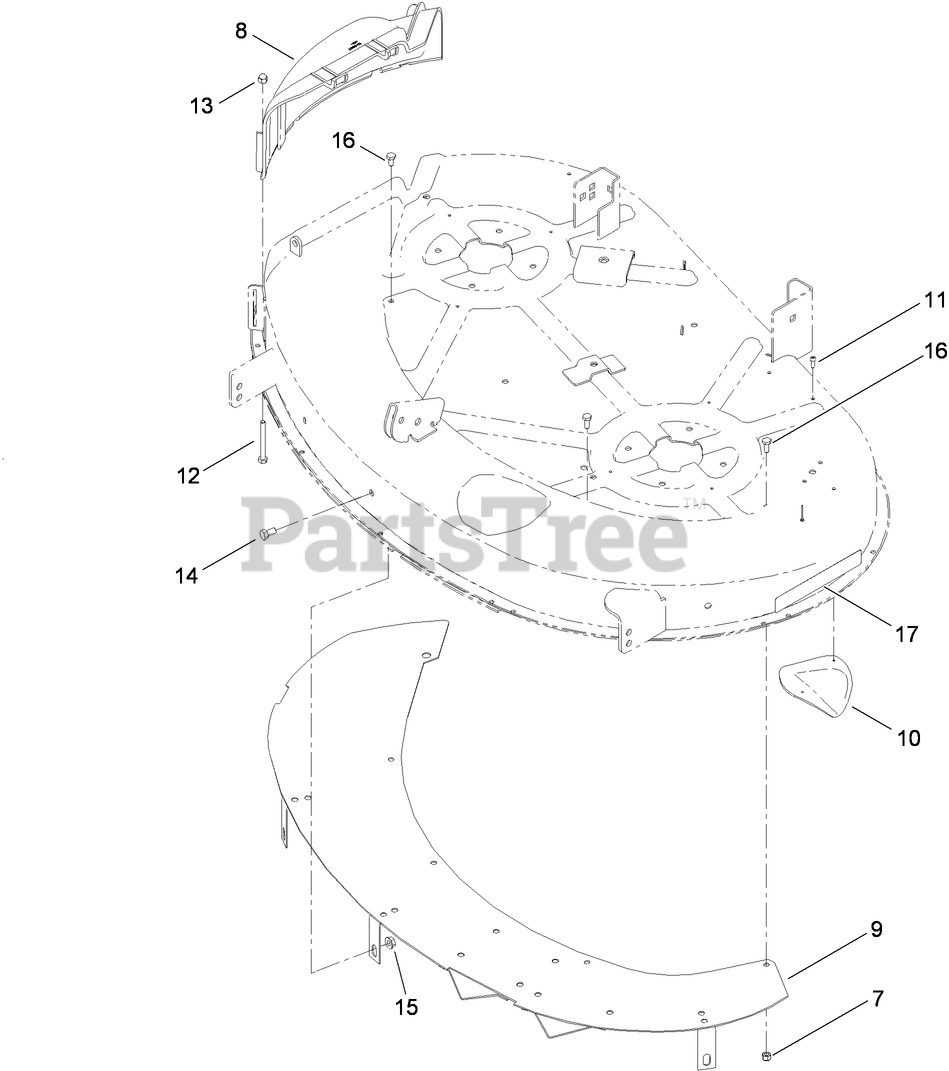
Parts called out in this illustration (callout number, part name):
7	NUT-LOCK, NI
8	COVER-DISCHARGE
9	BAFFLE UPPER ASM
10	PLATE-KICKER
11	SCREW-PPH
12	SCREW-HH
13	NUT-CAP
14	SCREW-HH
15	NUT-HF
16	SCREW-HH
17	DECAL-RECYCLER
